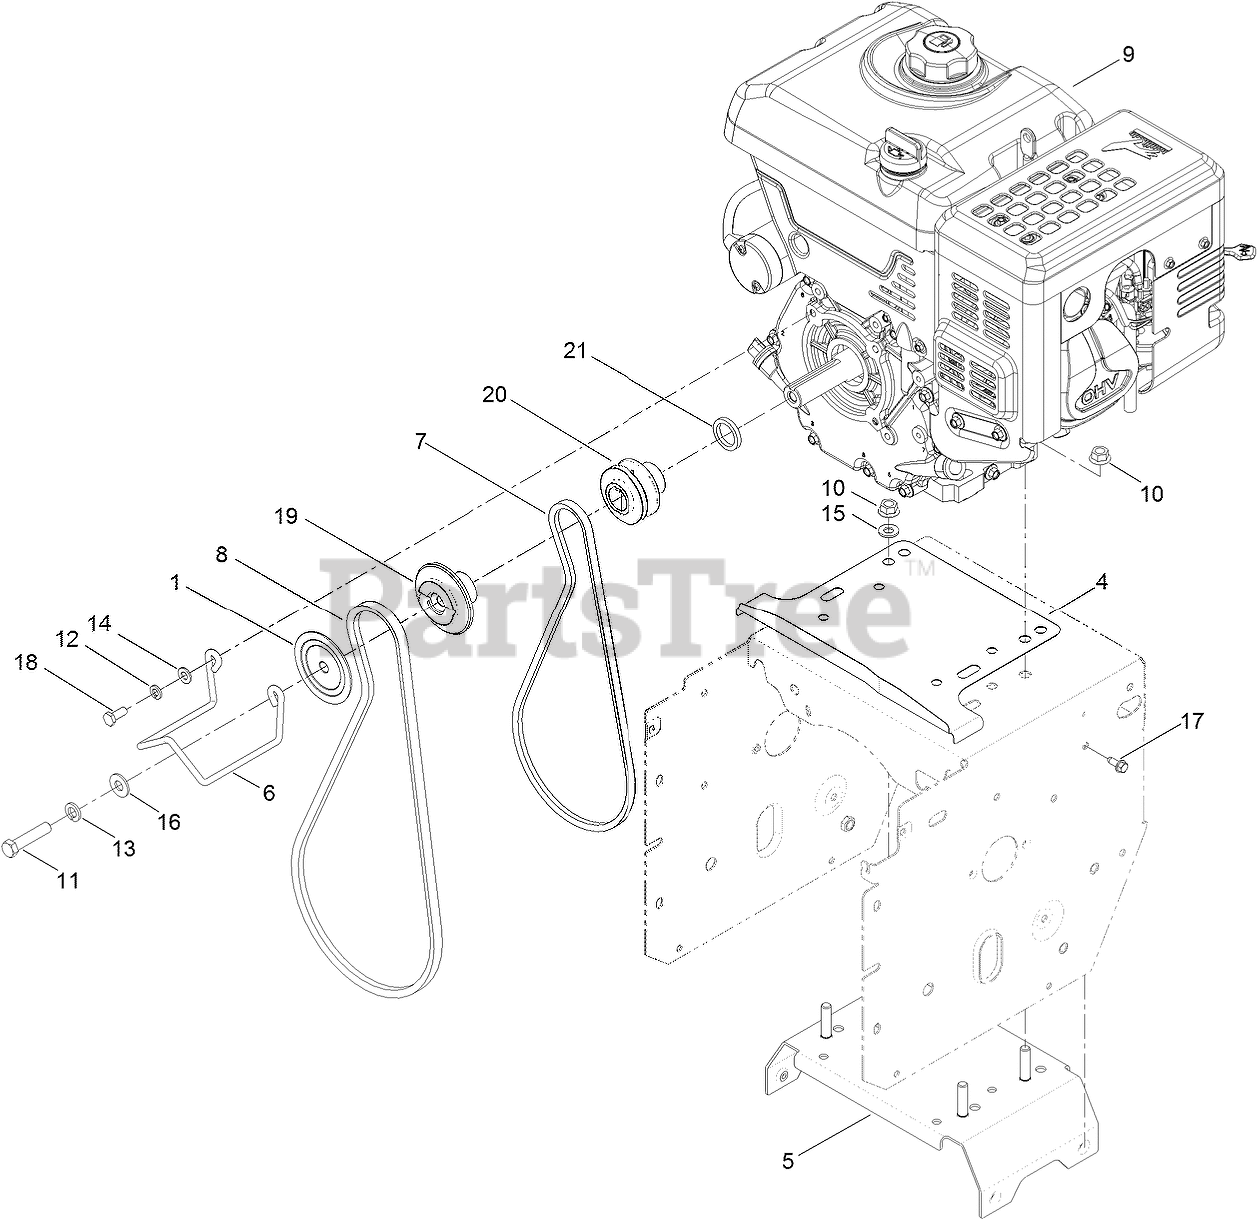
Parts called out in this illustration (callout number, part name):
1	SHEAVE-HALF, IMPELLER
4	SHIELD-DRIVE
5	FRAME BRACE ASM
6	GUIDE-BELT
7	V BELT-TRACTION
8	BELT-V
10	NUT-HF
11	SCREW-HH
12	WASHER-LOCK
13	WASHER-LOCK
14	WASHER-PLAIN
15	WASHER-FLAT
16	WASHER-FLAT
17	SCREW-HWH
18	SCREW-HH
19	PULLEY-ENGINE, IMPELLER
20	PULLEY-TRACTION
21	SPACER-HARDENED
